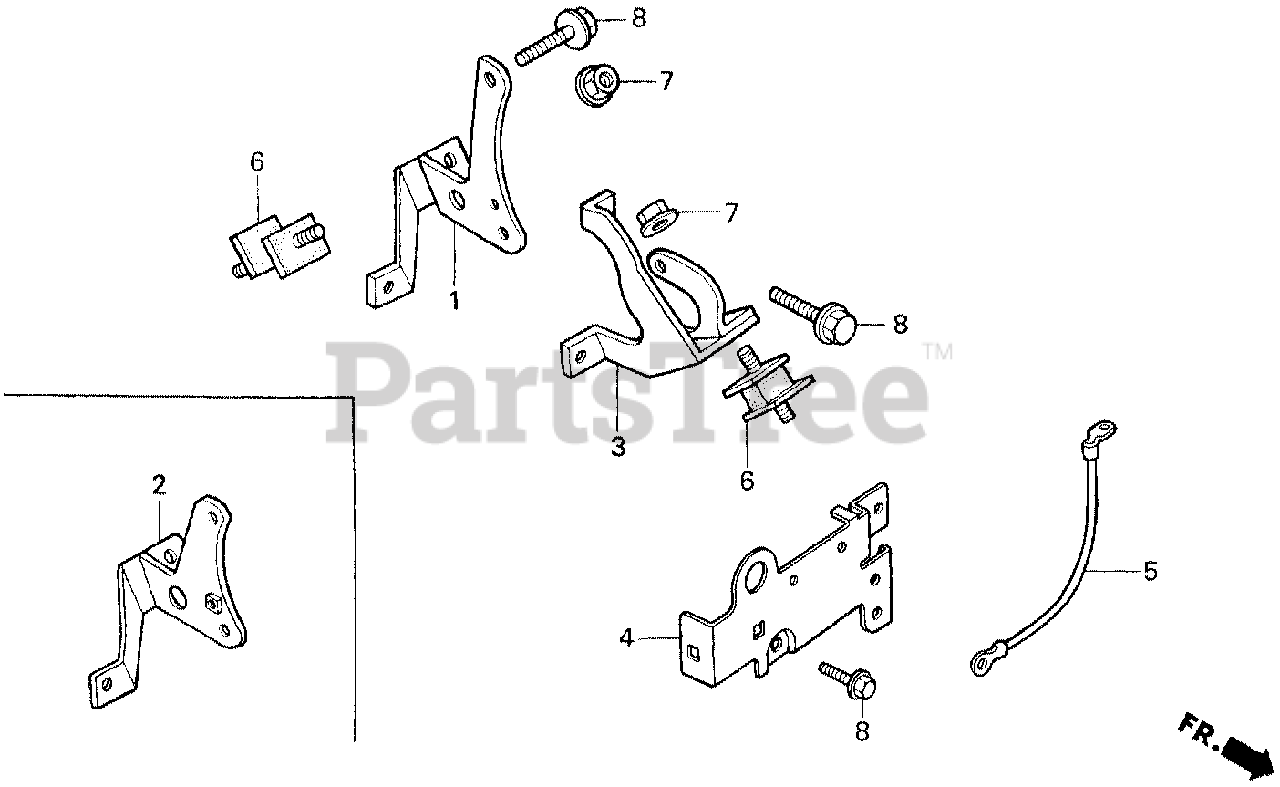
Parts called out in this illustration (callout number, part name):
2	STAY, ENGINE MOUNTING
3	STAY, L. ENGINE MOUNTING
4	HOOK, ENGINE
5	CABLE, BATTERY GROUND
6	RUBBER, ENGINE SETTING
7	NUT, FLANGE (10MM)
8	BOLT, FLANGE (8X20)
